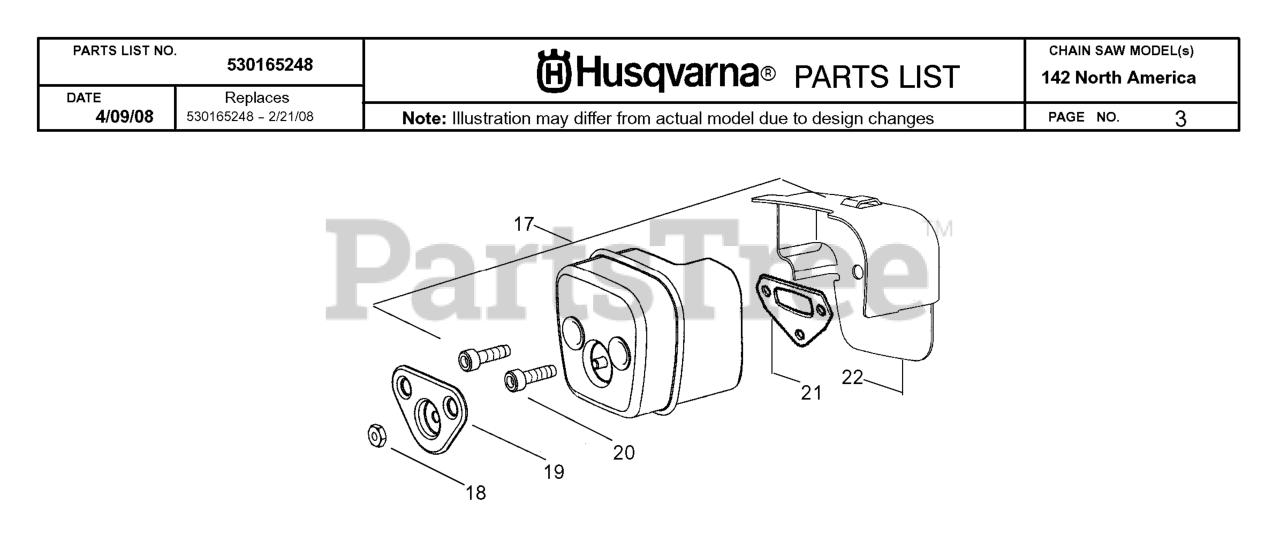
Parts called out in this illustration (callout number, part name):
17	MUFFLER KIT
18	NUT-BRASS
19	COVER BOLT
20	SCREW MUFFLER
21	GASKET-MUFFLER
22	BACKPLATE, MUFFLER
